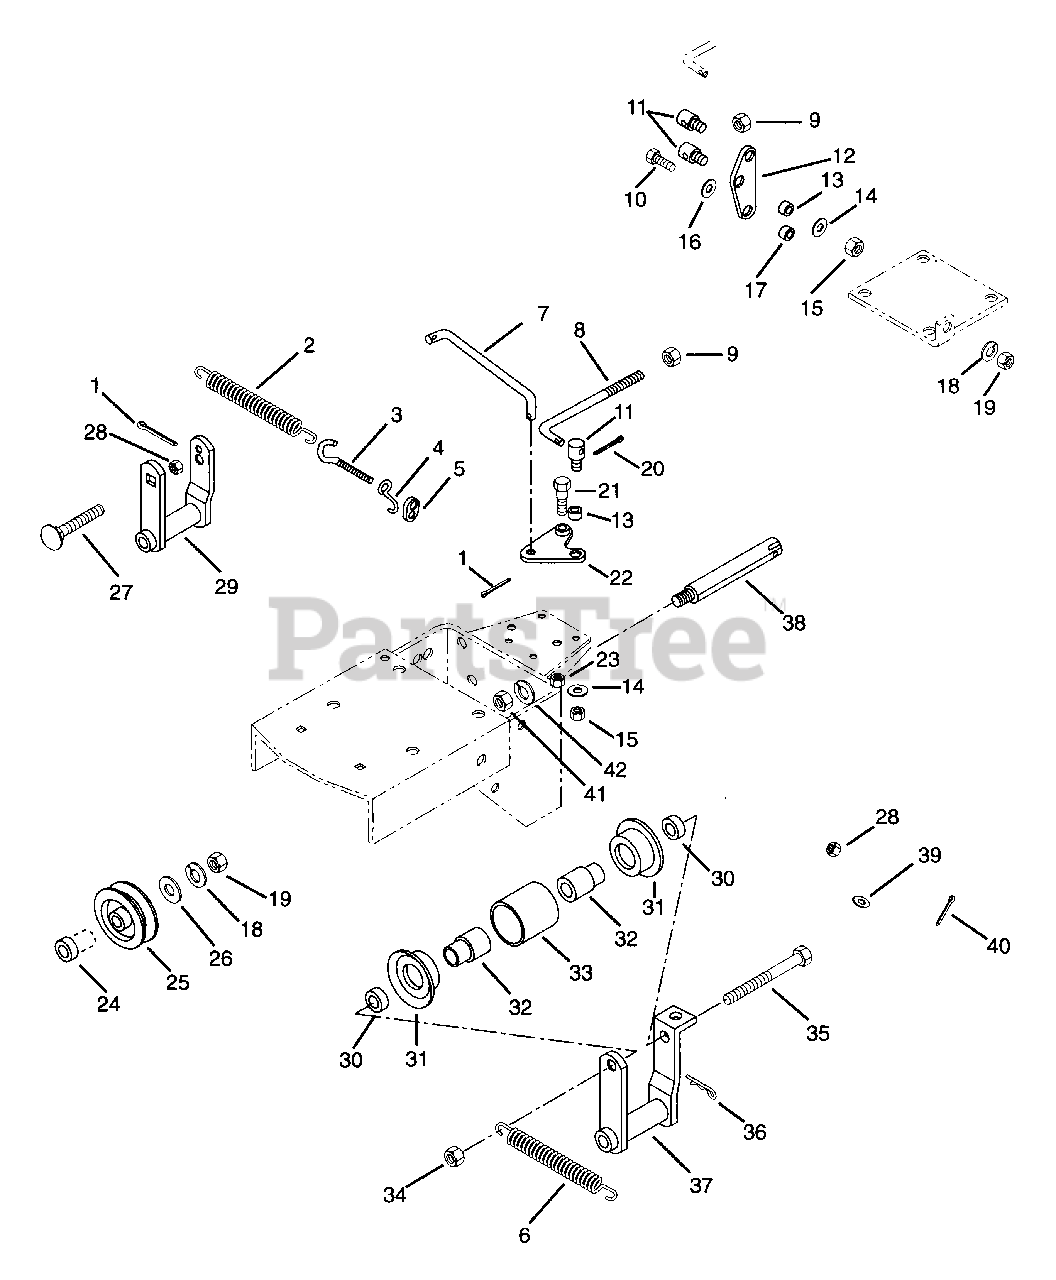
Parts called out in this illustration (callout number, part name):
1	PIN-COTR .12X1.0 PL
2	SG-TENS .105X.812X3.88 WLD 15
3	EYE BOLT
4	LINK-CLUTCH
5	RETAINING NUT
6	SG-TENS .063X.44X2.81 WLD 18
7	CROSS LINK
9	NUT-JAM .375-16 PL
10	BLT-HEX .31-18X1.00 PL GR 2
11	UNIVERSAL ROD ADAPTER
13	SPACER .63 X .50 X .18
14	WSHR-FL-STL .505X1.000X.062
15	NUT-LK-CTR .50-13
16	WSHR-FL-STL .390X.750X.125 PL
17	SPACER BUSHING .5 X .32 X .21
18	WSHR-LK .312X.097 PL HVY
19	NUT-HEX .312-18
20	PIN-COTR .15 X 1.0 PL
21	BLT-SHLDR .38-16X1.25
22	PIVOT LEVER
23	NUT-LK-CTR .375-16 GR A PL
24	SPCR, BRG .315X.50X.688X.281
25	IDLER
26	WSHR-FL-STL .38X.875X.083 PL
27	BLT-RDHDSQNK .31-18X1.38SHT PL
28	NUT-LK 8-32 GR A PL
29	REVERSE IDLER ARM
30	BSHG, SPCR.500X.750X.321 PM
32	BEARING SPACER
34	NUT-LK .312-18 GR A PL
35	BLT-HEX .31-18X4.00 PL GR2
36	PIN-HAIR INT .06X.18X.77
37	IDLER ARM
38	IDLER PIN
39	WSHR-FL-STL .328X.875X.062 PL
40	PIN-COTR .09X1.0 PL
41	NUT-HEX .375-16
42	WSHR-LK .375X.094 MED PL
